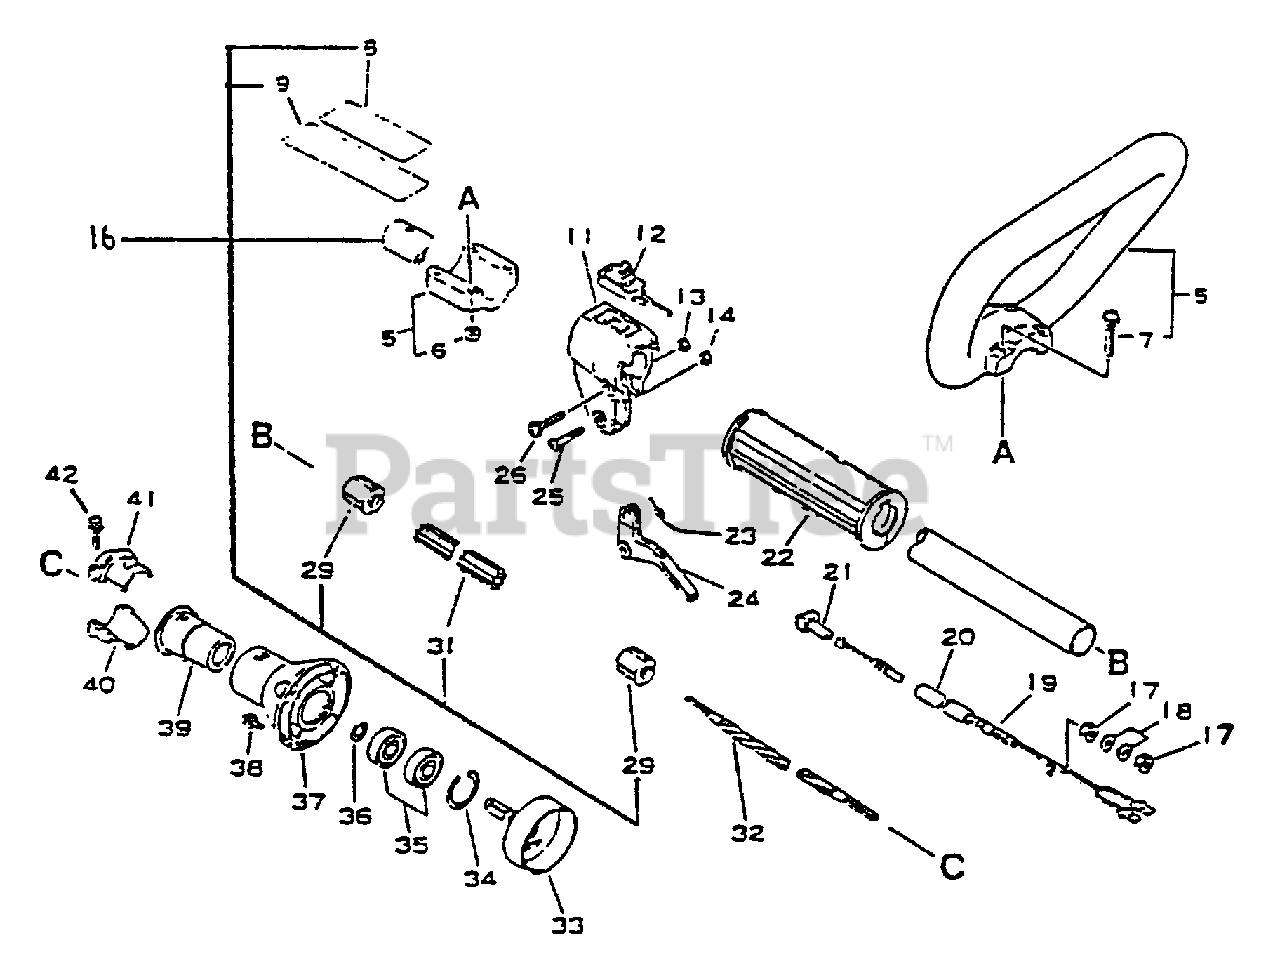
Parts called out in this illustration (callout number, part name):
5	LOOP HANDLE ASSY
6	NUT M5
7	SCREW 5×35
8	LABEL - CAUTION
9	LABEL - CAUTION
11	BRACKET, THROTTLE CONTROL
12	IGNITION SWITCH ASSY
13	NUT M5
14	LOCKNUT - 5
16	MAIN PIPE ASSY 25×1500
18	WASHER 6.5×11.5×0.8
19	CABLE, THROTTLE
21	GUIDE, CABLE
22	GRIP, HANDLE
23	SPRING, THROTTLE
24	TRIGGER, THROTTLE
26	SCREW 5×30
31	LINER, FLEXIBLE 21.6×1420
32	DRIVESHAFT - FLEXIBLE L= 1522
33	DRUM, CLUTCH
34	RING, SNAP 28
35	BEARING, BALL 6001
36	RING, RETAINING - 12
37	CASE, CLUTCH
38	SCREW 5×16
40	HOLDER, MAIN PIPE - UPPER
42	BOLT - 5×25
